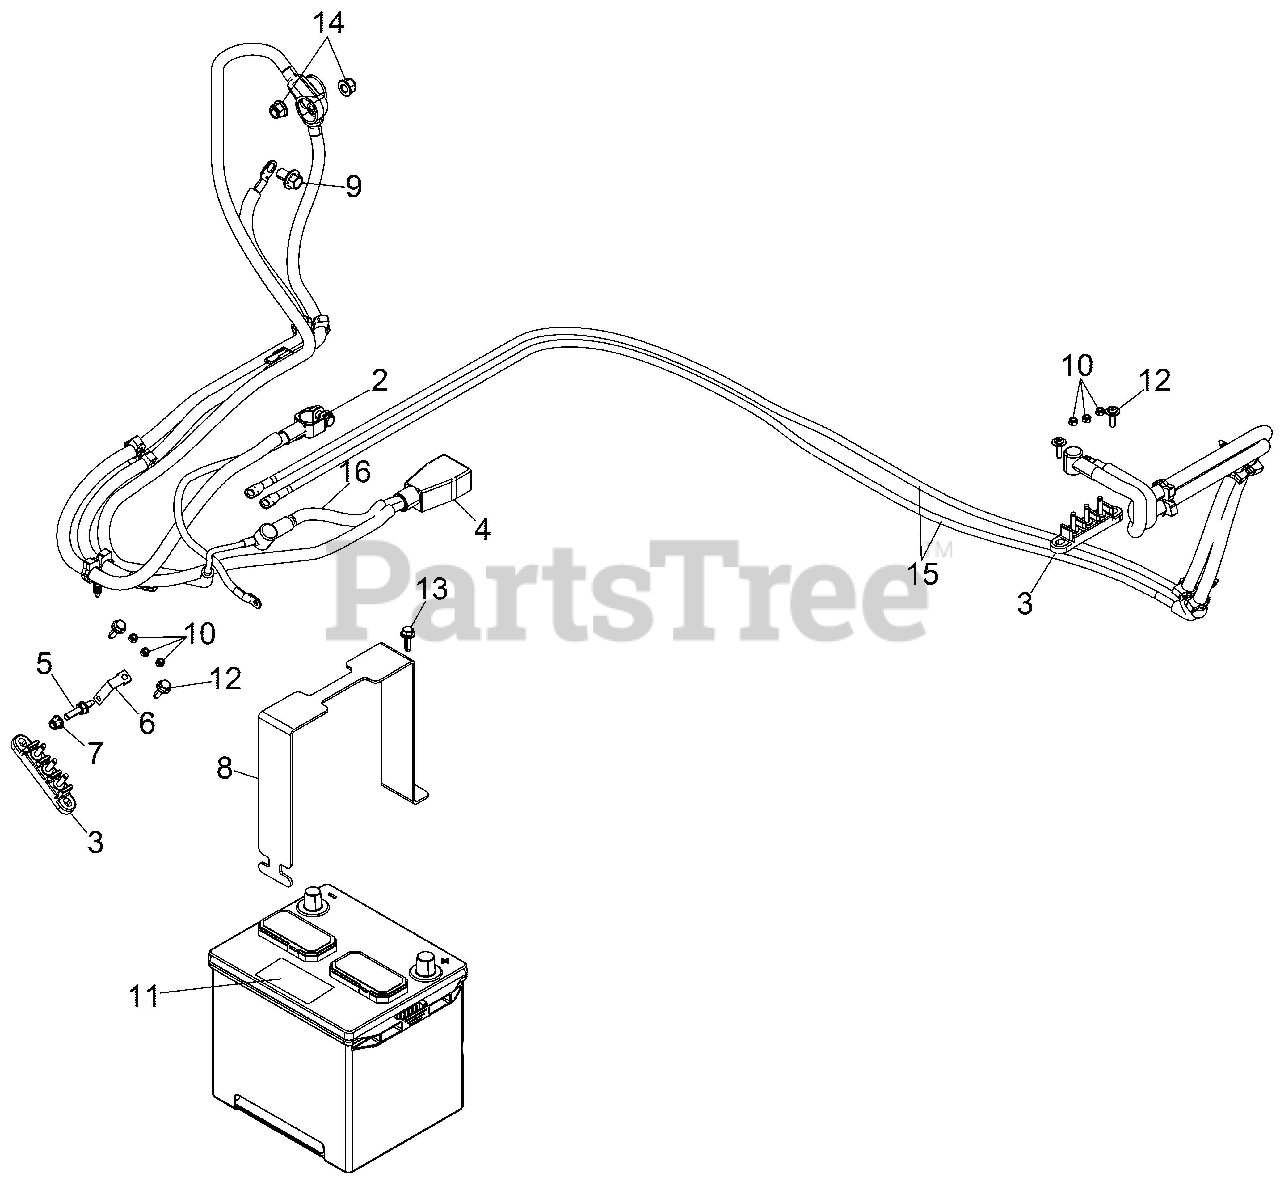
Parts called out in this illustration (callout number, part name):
2	ASM-CABLE, BAT TO GROUND/TERM
3	BLOCK-TERMINAL,3 POST
4	ASM-CABLE, BAT TO STARTER SOL
5	STUD-M6X1.0X19-M6 TAPTITE
6	STRAP-GROUND
7	NUT-M6 FLANGE,NYLOK
8	BRKT-BATTERY STRAP GALV
9	NUT,NYLOK(10)
10	NUTS-10-32 KEPS
11	DECAL, BATTERY
12	SCR-10-24X3/4 PH/TX/TRI-SEMS Y
13	SCR-M6X1.0X20,HXHD,FLG,TDFM,BL
15	CABLE, TERMINAL BLOCK, GROUND
16	CABLE-ALTERNATOR,BATT
